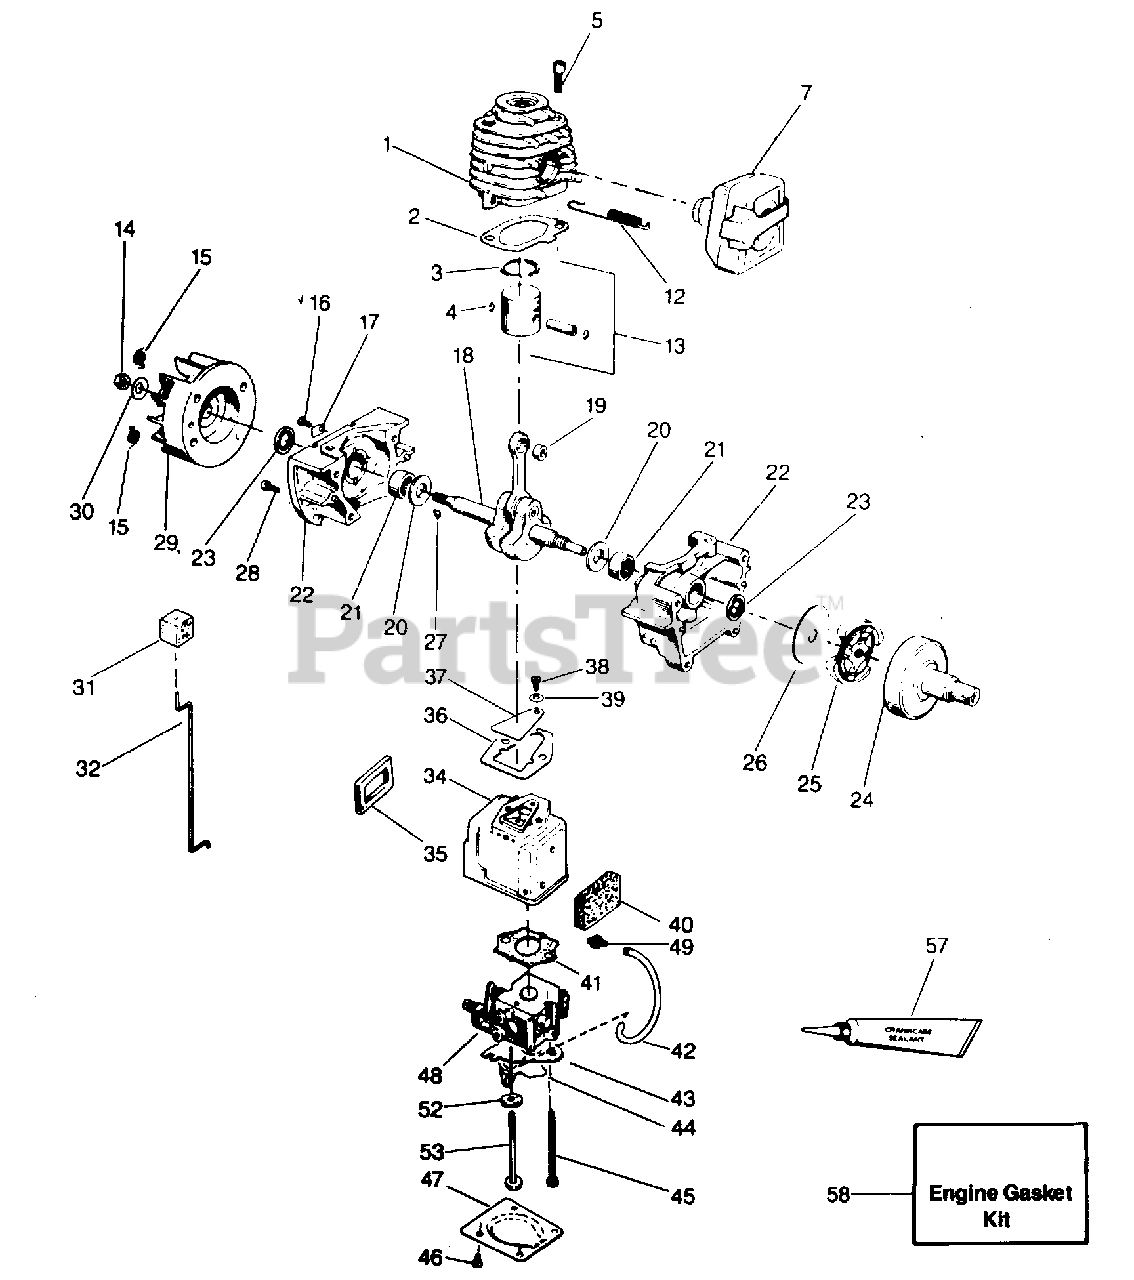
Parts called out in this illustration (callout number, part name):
1	Cylinder
2	Gasket - Cylinder
3	Ring - Piston
4	Retainer - Wrist Pin
5	Screw - 1/4 - 20 x 3/4" - Hex Soc.' Hd. - Cylinder
12	Spring - Muffler Attachment
13	Piston Kit (Incl. #3, 4 & Pin)
14	Nut - Flywheel
15	Spring - Starter Dog
16	Screw - 8 - 32 x 5/16" - Choke Wire Clamp
17	Clamp - Choke Wire
18	Ass'y. - Crankshaft & Bearing
19	Bearing - Wrist Pin
20	Washer - Thrust - Crankcase
21	Bearing - Crankshaft
22	Crankshaft Ass'y. (Incl. #21, 23 & Qty. 4 of #28)
23	Seal - Crankcase
24	Drum & Coupling Assembly
25	Kit - Clutch Assembly (Incl. Washer)
26	Kit - Clutch Washer
27	Key - Flywheel
28	Screw - 10 - 24 x 5/8" - Fil. Hd. Crankcase
29	Flywheel Assembly (Incl. #15)
30	Washer - Flywheel
31	Boot - Choke Wire
32	Choke Wire
34	Carburetor Housing
35	Seal - Carburetor Case
36	Gasket - Carburetor Case to Crankcase
37	Reed Valve
38	Screw - 6 - 19 x 5/16" - Pan Hd. - Reed Valve
39	Washer - Reed Valve Screw
40	Seal - Carb. Case (Sponge)
41	Gasket - Carburetor
42	Line - Fuel - Carburetor
43	Guide - Plate Choke Wire
44	Shutter - Choke
45	Screw - 10 - 24 x 1-7/8" - Carburetor
46	Screw - 8 - 18 x 9/16" - Pan. Hd. - Carburetor Case Cover
47	Cover - Carburetor Case
48	Carburetor - WA -149
49	Type 1, 2 & 3
52	Washer - Waver
53	Screw - 10 - 24 x 2-1/18" Carb. Shoulder
57	Sealant - Crankcase (not supplied with unit)
58	Kit - Engine Gasket (Inc. 2,23,31,35,36,40, 41)
